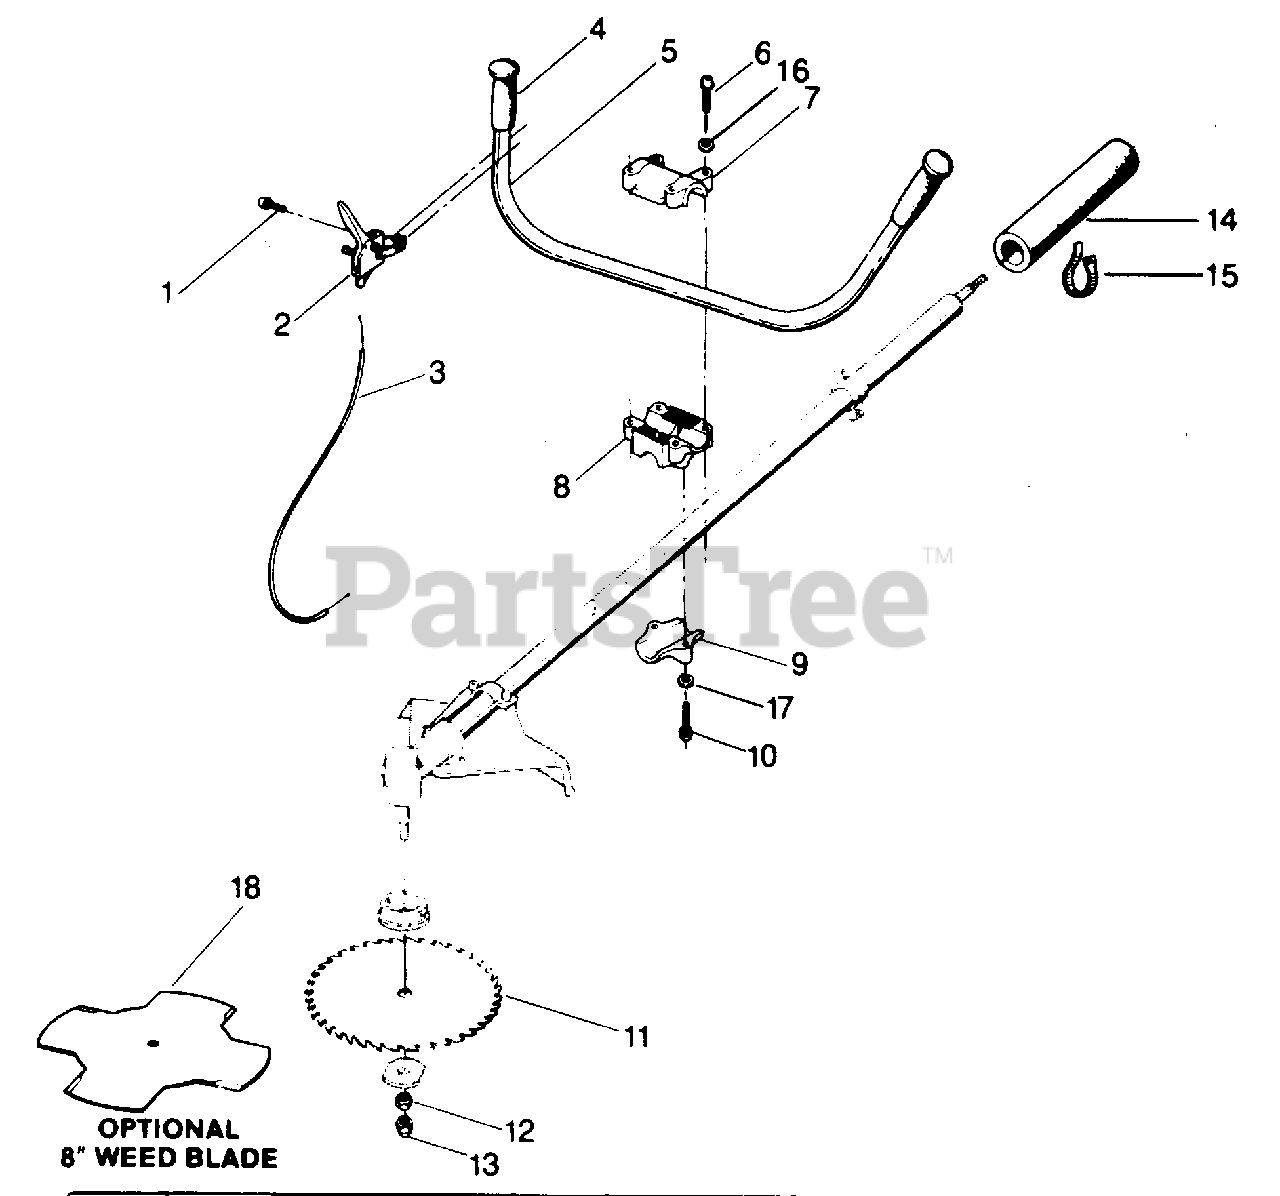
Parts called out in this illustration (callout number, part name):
1	Screw - Phil. Hd. - 5 x 25mm.- Throttle Control
2	Ass'y. - Throttle Control
3	Cable - Throttle
4	Grip - Handlebar
5	Handlebar
6	Bolt - Clamp - Top
7	Cover - Top - Clamp
8	Clamp - Handlebar
9	Cover - Bottom - Clamp
10	Bolt - Clamp - Bottom
11	Brush Blade
12	Lock Nut - Blade
13	Cap - Nut - Blade
14	Drive Shaft Pad
15	Tie Strap
16	Lockwasher - 10
17	Lockwasher - 10
18	8 inch - Weed Blade - Optional
